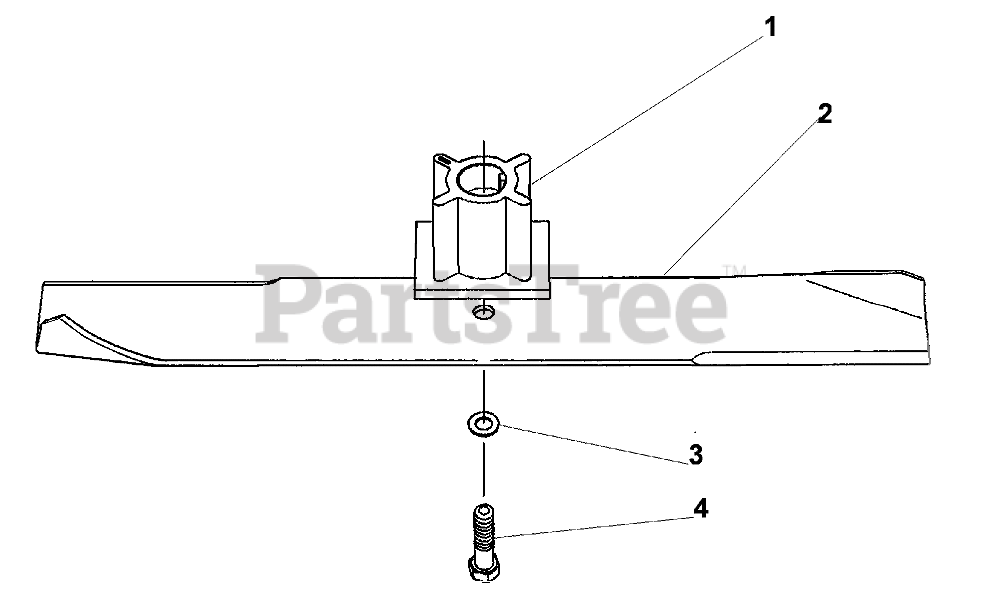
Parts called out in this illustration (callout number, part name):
1	RETAINER-BLADE
2	BLADE-RECYLER
3	WASHER-LOCK
4	BOLT-BLADE
